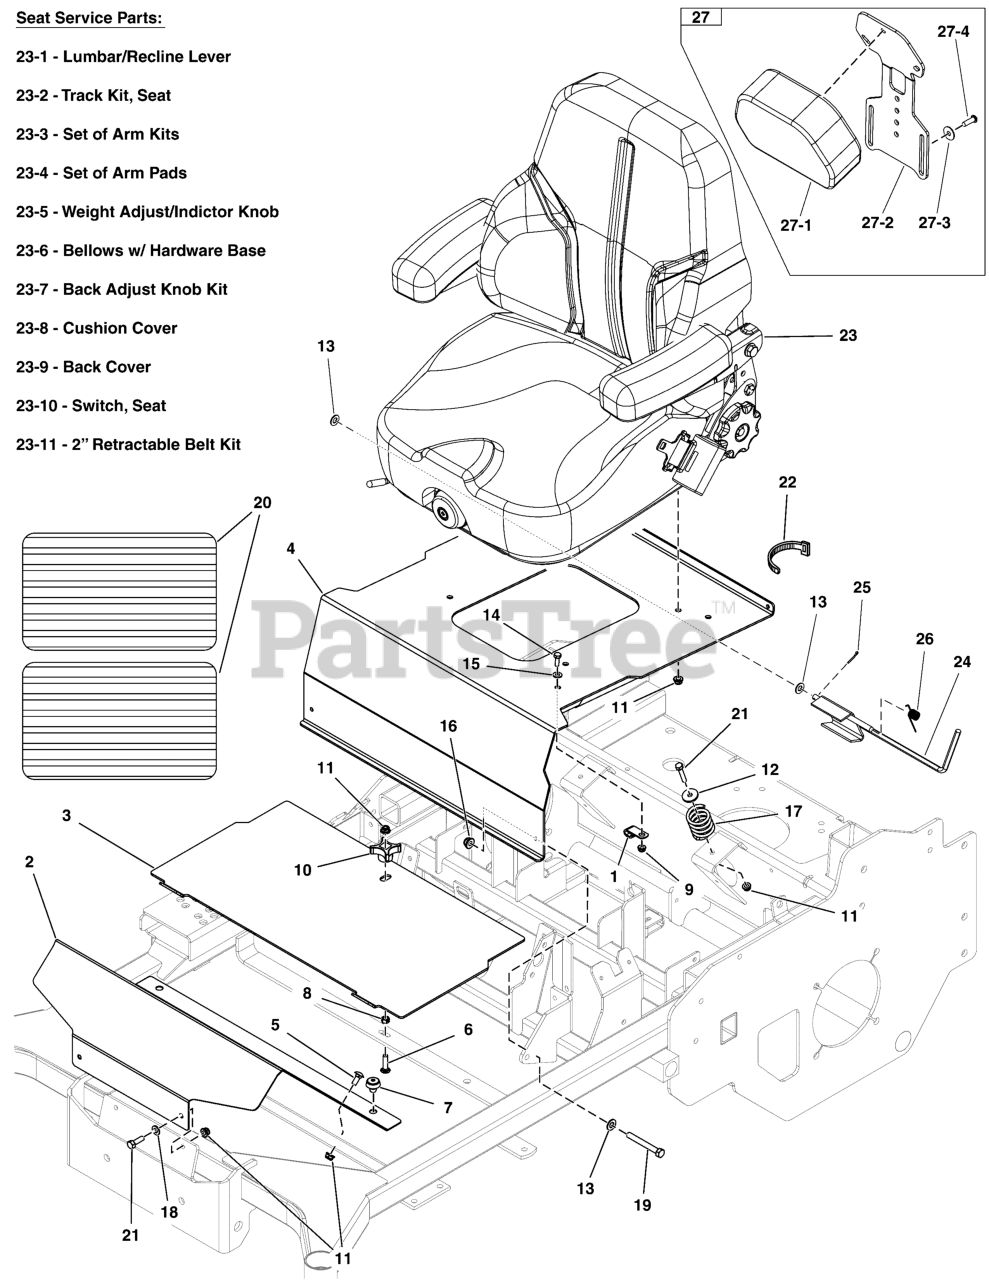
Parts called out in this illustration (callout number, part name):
1	CLAMP, 5/16", DOUBLE, WIRE & TUBE
2	PLATE, RIGID FLOOR, S320Z - RED
3	PLATE, REMOVABLE FLOOR, 200XT - RED
4	ASSM, SEAT PLATE W/DECAL-DOM (5418271B)
5	BOLT, 5/16-18 X 3/4, CARRIAGE, GD5, CZ
6	BOLT,5/16-18X1.500,CARRIAGE,SQ,GR5,ZC/CL
7	MNT, VBRTN, RBBR
8	NUT, 5/16-1/8, HEX, CNTR LK, ZINC PHOS/OIL
9	NUT, 1/4-20 Hex Nylock Flange
10	KNOB-INT THR .312-18 4-ARM 2.12WD 1.06LG
11	NUT, 5/16-18 HEX NYLOCK FLANGE NUT
12	WASHER, .34 X 1.25 X 10 GA
13	WASHER, 3/8 SAE
14	BOLT, 1/4"-20 X 3/4" GD5 YZ
15	WASHER, 1/4 SAE
16	NUT, 3/8 - 16 HEX NYLOCK FLANGE
17	SPRING, SEAT SUPPORT
18	WASHER, 5/16" SAE
19	BOLT, 3/8-16 X 3" GD5 CZ
20	SAFETY WALK, 10.00 X 19.00
21	BOLT, 5/16-18 X 1" GRD5 YZ
22	TIE, SELF-LOCKING, 6"
23	SEAT, HIGH BACK,SUSP,SWITCH & SEAT BELTS
23-1	LUMBAR/RECLINE/ISO LVR W/ RLL PIN BS
23-2	4" SINGLE LOCKING TRACKS BASE
23-3	SET OF ARM KITS
23-4	SET OF ARM PADS
23-5	WEIGHT ADJUST INDICATOR KNOB ASSY BASE
23-6	BELLOWS W/ HARDWARE BASE
23-7	BACK ADJUSTMENT KNOB KIT
23-8	CUSHION COVER FORM I3M, 314659VN584
23-9	SEAT BACK COVER
23-10	SWITCH, SEAT
23-11	2" RETRACTABLE BELT KIT
24	WELD, SEAT LATCH HOOK, W/ SPRING - BLK
25	PIN, 3/32 X 0.750, COT, ZINC/CLEAR
26	SPRING, TORSION, LH, .0625OD
27	KIT, HEAD REST
27-1	HEAD REST HIGH BACK SEAT
27-2	PLATE, MOUNTING BRACKET, HEADREST - BLK
27-3	WASHER, FENDER, 1.00 OD X .315 ID X .055
27-4	SCREW, 5/16-18X1, BUT HD, BLK, W/PATCH
